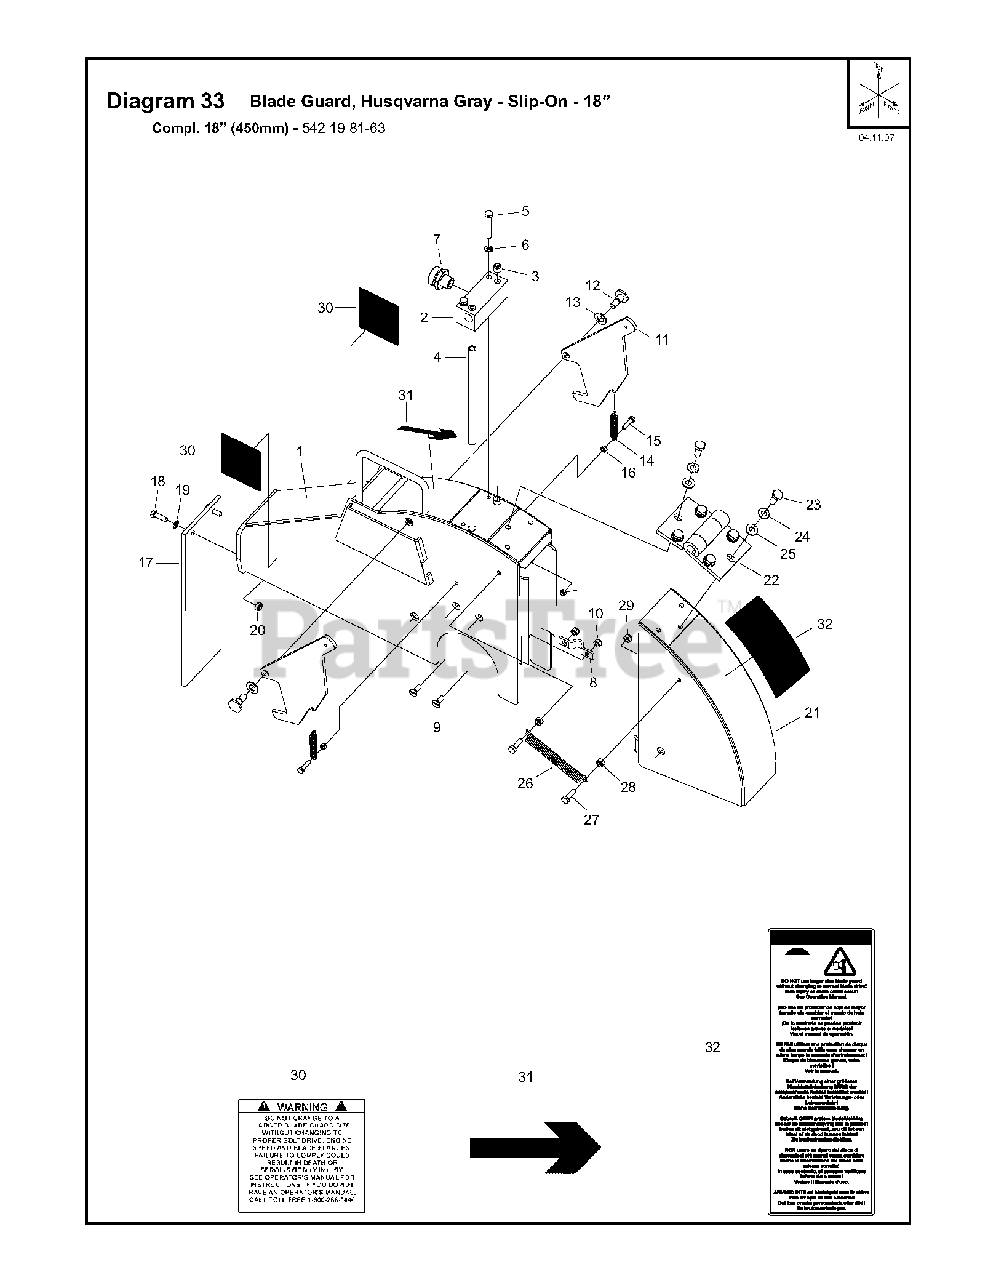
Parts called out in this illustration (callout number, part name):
1	REAR BLD GD WLDMT 18S.PC H-GRY
2	MANIFOLD. WATER ASSY
5	HHCS. M6 x 1.0 x 45 DIN931 Z/P
6	LOCKWASHER. SPLIT M6
7	FITTING. HOSE .375 x .75GHT
9	FLHMS. M6 x 1.0 x 16mm SLOT
10	LOCKNUT. FIBER M6 DIN 985
13	WASH.FIBER 10Dx.40625IDx.09375
15	HHCS. M5 x 0.8 x 20 DIN933 Z/P
16	NUT
18	GRIP HANDLE DLM
19	WASHER
20	LOCKNUT. FIBER M6 DIN 985
21	FRNT BLGD WLD 18S MET PC H-GRY
23	HHCS. M8 x 1.25 x 20 DIN933 ZP
24	LOCKWASHER. STAR EXTERNAL M-8
25	WASHER
27	GRIP HANDLE DLM
28	NUT
29	LOCKNUT. FIBER M6 DIN 985
